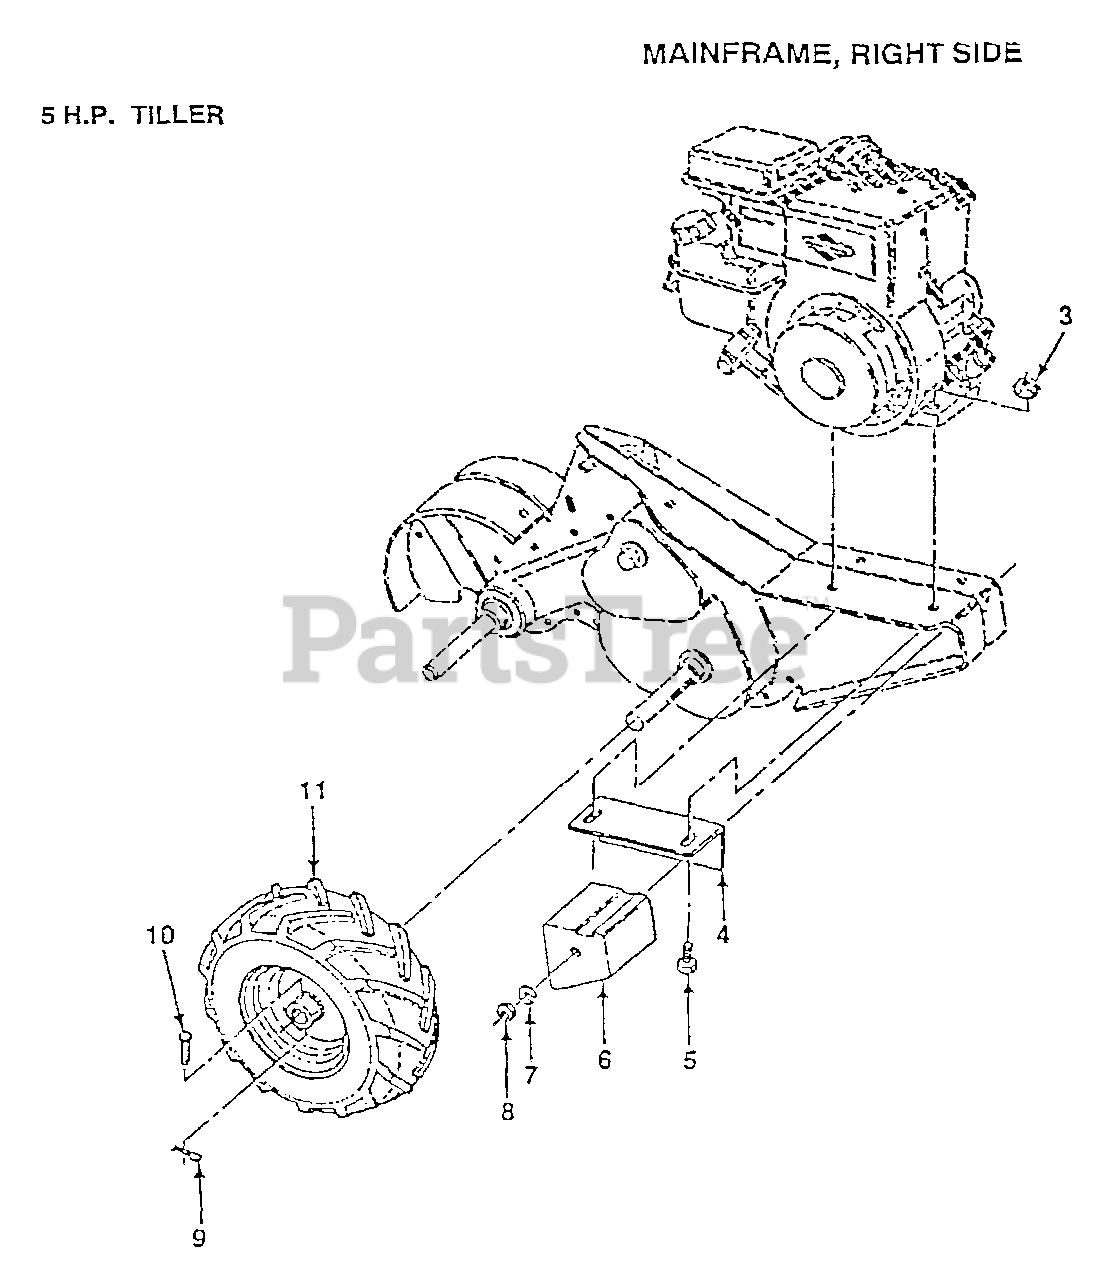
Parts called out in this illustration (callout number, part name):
4	BRACKET RH CRT
5	BOLT.HEX.5/16-1.5
6	COUNTERWEIGHT CRT
7	LOCKWASHER
8	NUT.HEX.3/8-16UNC
9	RETAINER M
10	RIVET.DRILL.1.75
11	TIRE.CHV.13X5.0-6
11	RIM
